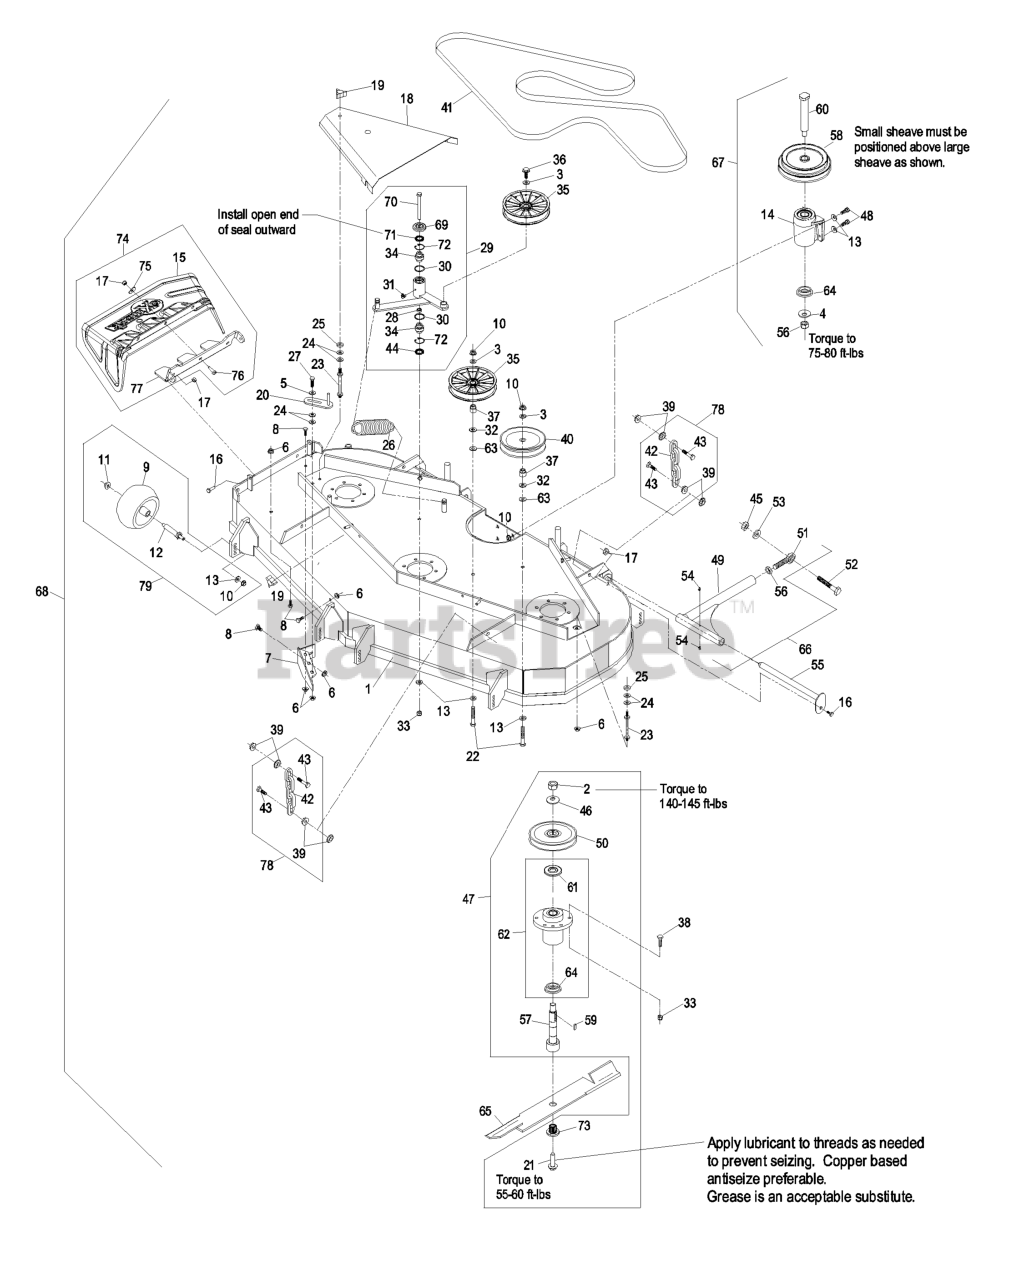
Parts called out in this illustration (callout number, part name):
1	ASM,DECK W/DECALS LZ604
3	WASHER-FLAT
4	WASHER-SPRING
5	WASHER-SPRING
7	WLD,BAFFLE DISCHARGE
8	SCREW-HH
9	ROLLER-SCALP, ANTI
10	NUT-HHF, WHIZ
11	Nut-Nyloc 3/8-16 Flg
13	WASHER-BELLEVILLE
14	KIT, JACKSHAFT ASSY
15	CHUTE,DISCHARGE
16	SCREW-HH
17	NUT-LOCK, NI
18	SHIELD,BELT
19	KNOB-3 PRONG
20	GUIDE-BELT
22	BOLT-CARR
23	STUD-SHIELD, BELT (SHORT)
24	WASHER-FLAT
27	SCREW-HH
29	KIT,DECK IDLER LZ/XP
31	FITTING-GREASE, 90 DEG
32	WASHER-FLAT
33	NUT-LOCK, NI
34	BEARING-SPHERICAL
35	PULLEY,IDLER 6"
36	SCREW-HHF
37	BUSHING-IDLER
38	SCREW-HH
40	PULLEY-IDLER
41	BELT,BLADE DRIVE
42	CHAIN-LIFT, DECK
43	SCREW-HH
44	SEAL-LIP, DOUBLE
45	NUT-HEX
47	ASM, CUTTER HSG COMPLETE
48	SCREW-HH
49	STRUT-DECK
50	SHEAVE,BLADE DRIVE 6.30
51	BALLJOINT-SPHERICAL
52	SCREW-HH
53	WASHER-LOCK
54	FITTING-GREASE
55	PIN-STRUT
56	NUT-HEX
57	KIT, SPLINED SPINDLE 103-
58	SHEAVE, JACKSHAFT DOUBLE
60	JACKSHAFT
61	GUARD-BEARING, TOP
62	KIT, CUTTER HOUSING
64	SPACER-GUARD, BOTTOM
66	STRUT ASM
67	KIT,JACKSHAFT 60/72-3750
68	Complete Deck Assy
69	GUARD-TOP
70	SCREW-HH
71	SEAL-LIP, SINGLE
72	RING-SNAP
73	BUSHING,SPLINED
75	WASHER-FLAT
76	SCREW-CARR
77	BRACKET,DISCHARGE CHUTE
78	DECK CHAIN ASM
